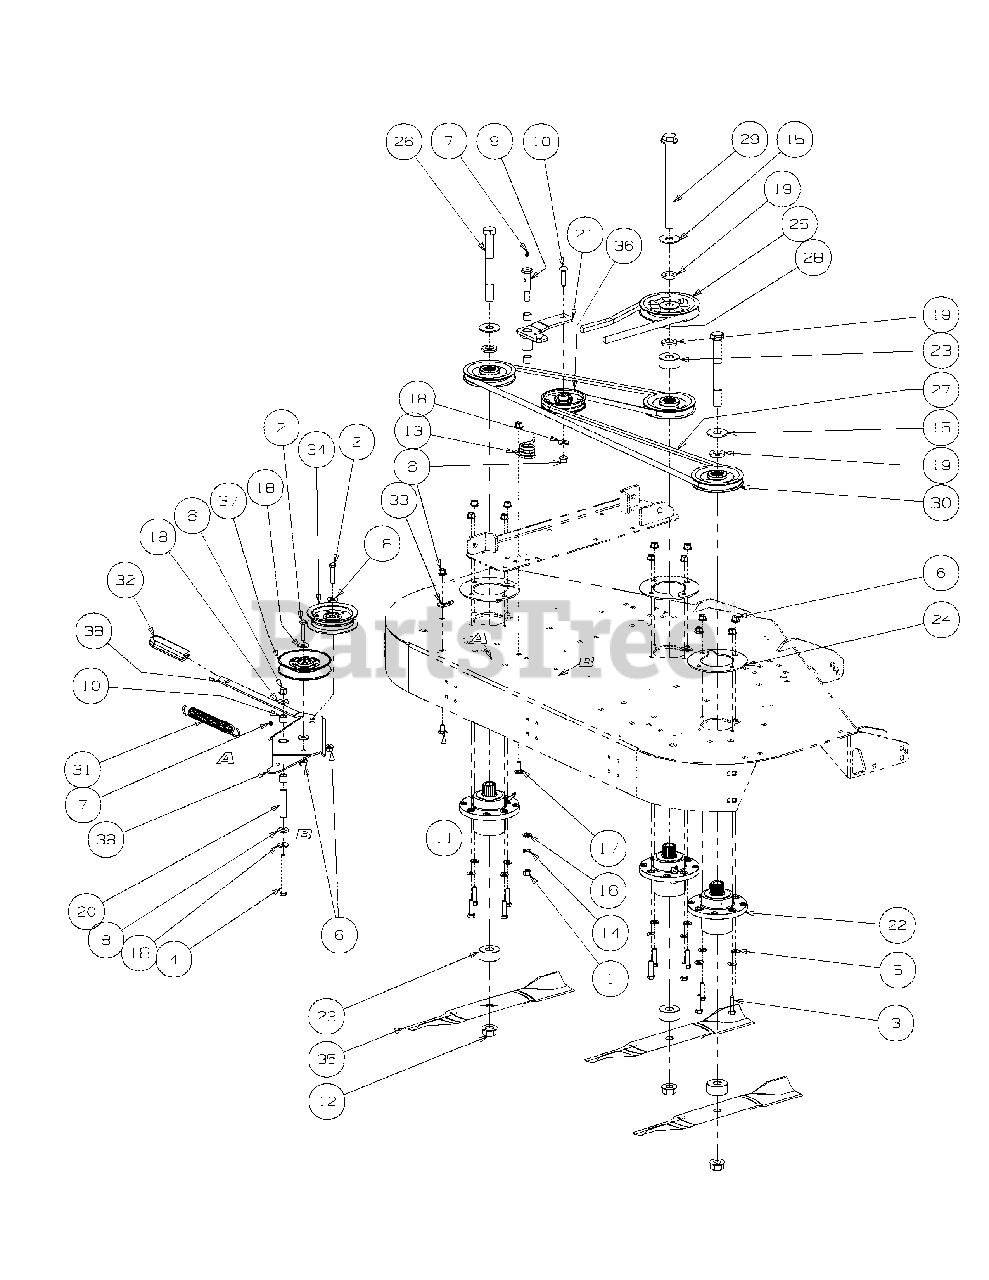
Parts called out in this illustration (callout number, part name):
1	Hex Nut, 7/16-14
2	Hex Cap Screw, 3/8-16 x 1-1/4
3	Hex Cap Screw, 3/8-16 x 1-1/2
4	Hex Cap Screw, 3/8-16, 4.00
5	Flat Washer, 3/8
6	Hex Nut, Flange Lock, 3/8-16
7	Grease Fitting, 1/4-28 x 3/16
8	Idler Washer
9	Shoulder Screw, 7/16-14
10	Hex Carriage Screw, 3/8-16, 1.75
11	Carriage Bolt, 3/8-16 x .75 Lg.
12	Flange Hex Nut, 3/4-16
13	Torsion Spring Idler
14	Lock Washer, 7/16
15	Flat Washer, .781 ID, 2.00 OD, .105
16	Flat Washer, .469 ID, .875 OD, .105
17	Carriage Bolt, 3/8-16 x 1
18	Flat Washer, .406 ID, 1.0 OD, .105
19	Spacer, .812 ID x .218 LG
20	Spacer, .39 ID x .625 OD x 2.75
21	Idler Arm Assembly, Deck Spindle includes:
21	Bearing
22	Spindle Assembly, Aluminum Fab Deck
23	Spacer, .760 ID x 2.000 OD x 1.1
24	Plate Support, Cast Aluminum Spindle
25	V Pulley, 5.774 OD
26	Hex Cap Screw, 3/4-16, 7.00
27	V Belt, A Section x 114.3
28	V Belt, B Section x 91.2
29	Hex Cap Screw, 3/4-16, 9.00
30	V Pulley, 5.00 OD
31	Spring Extension, .94 OD x 7.57
32	Idler Tension Handle Grip
33	Tension Spring Bracket
34	Idler Pulley, 4.06 OD w/Deep Flange
35	Hi-Lift Blade, 19.0, 0.756
36	Idler Pulley, 4.06 Dia.
37	Idler Pulley, 5.06 Dia.
38	Idler Arm Assembly includes:
38	Bearing
